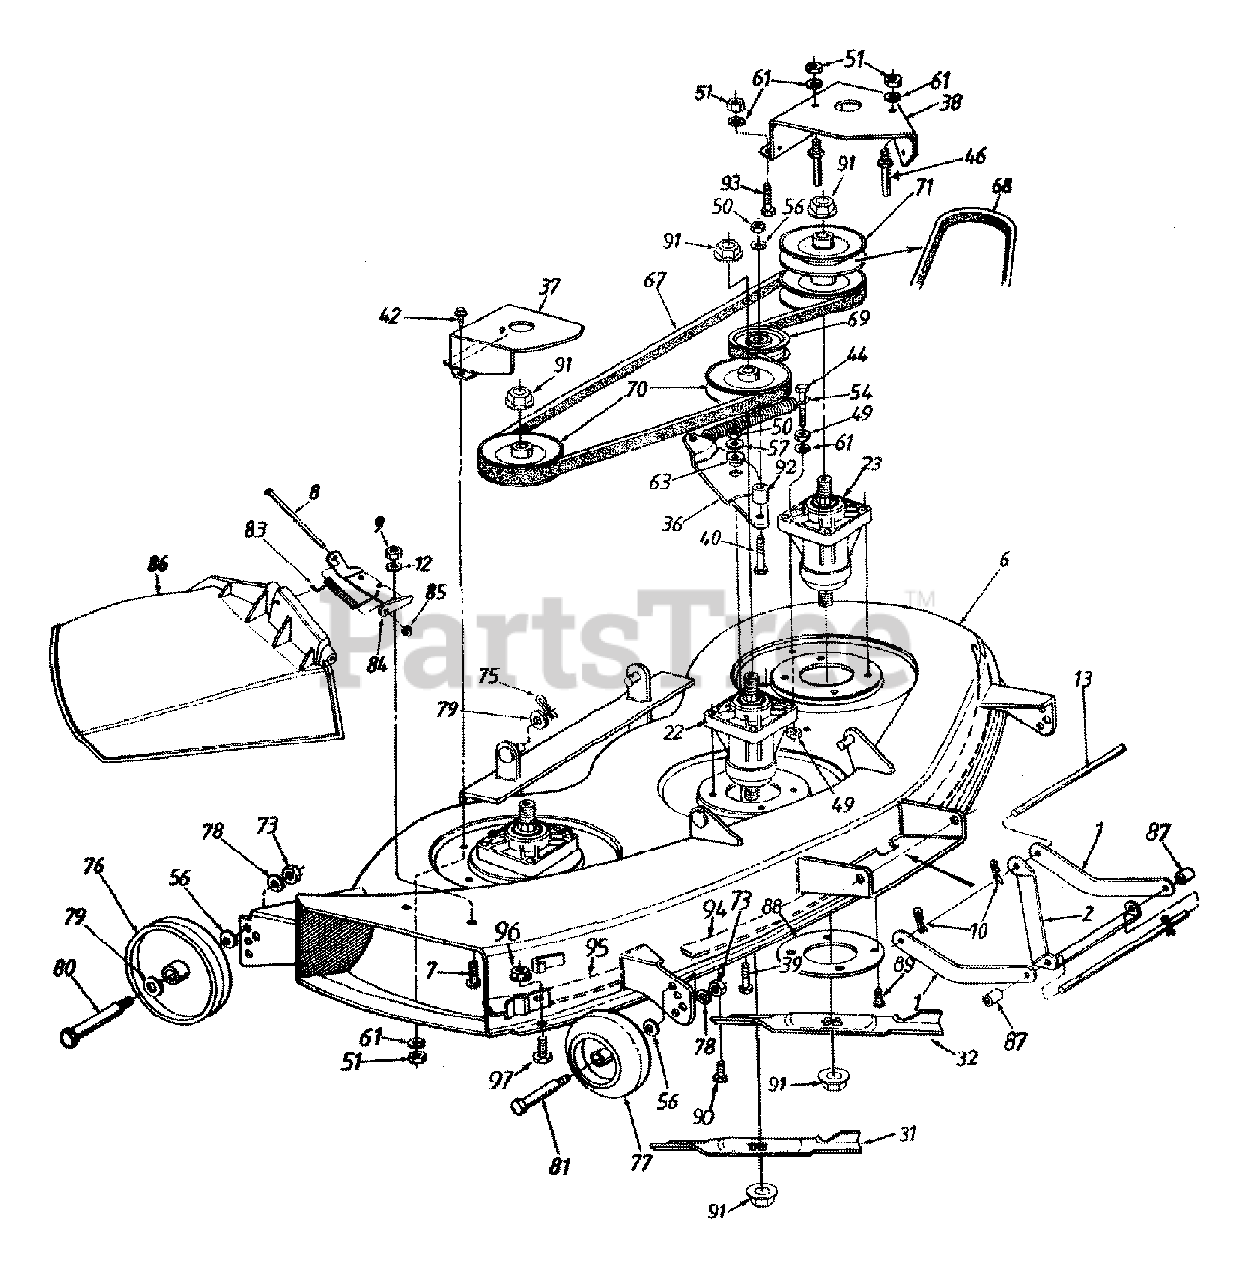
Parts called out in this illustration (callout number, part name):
8	Hinge Pin
9	Hex Nut 1/4-20 Thd.
12	Bell-Wash. 1/4" I.D.
13	Deck Connecting Rod
22	Spindle Ass'y. (R.H. & Center)
23	Spindle Ass'y. (L.H.)
31	Blade 14.88" Lg. (Middle)
32	Blade 16.28" Lg. (R.H. & L.H.)
39	Hex Bolt 3/8-24 x 1.0" Lg.
40	Hex Bolt 3/8-24 x 2" Lg.
42	Hex Wash. Hd. Tap-Scr. 1/4-20 x .5" Lg.
44	Hex Bolt 1/4-28 x 1.5" Lg.
46	Belt Guard Pin 1/4" Dia.
49	Hex Nut 1/4-28 Thd.
50	Hex Nut 3/8-24 Thd.
51	Hex Nut 1/4-20 Thd.
54	Extension Spring 6.17" Lg.
56	Bell-Wash. .38" I.D. x .88" O.D.
57	Bell-Wash. .39" I.D. x 1.13" O.D.
61	L-Wash. 1/4" I.D.
63	Shld. Spacer .625" I.D.
67	V-Belt
68	V-Belt
69	Fl-Idler Pulley 3.5" O.D.
70	Pulley 5.0" Dia.
71	Double Pulley 5.0" Dia.
73	Hex Nut 3/8-16 Thd.
75	Intern. Cotter Pin 3/8 Dia.
76	Deck Wheel 5" Dia.
77	Deck Wheel w/Insert 5" Dia.
78	L-Wash. 3/8" I.D.
79	Fl-Wash. .531" I.D.
80	Shoulder Bolt .498" Dia. x 1.64" Lg.
81	Shoulder Bolt
83	Torsion Spring
84	Hinge Mtg. Brkt.
86	Chute Ass'y. Comp.
87	Spacer 5/8" I.D. x 7/8" O.D.
90	Hex Wash. Hd. Scr. 5/16-18 x .75" Lg.
91	Hex Flange Nut 5/8-18 Thd.
92	Spacer .38" I.D.
93	Hex Bolt 1/4-20 x .5" Lg.
96	Hex Sems Nut 1/4-20 Thd.
97	Carriage Bolt 1/4-20 x .5" Lg.
17258A-0648	Deck Belt Cover, 46" Black - TECH GRAY (0648)
17258A-0665	COVER:BELT:DECK 46 - YARDMAN GREEN (0665)
